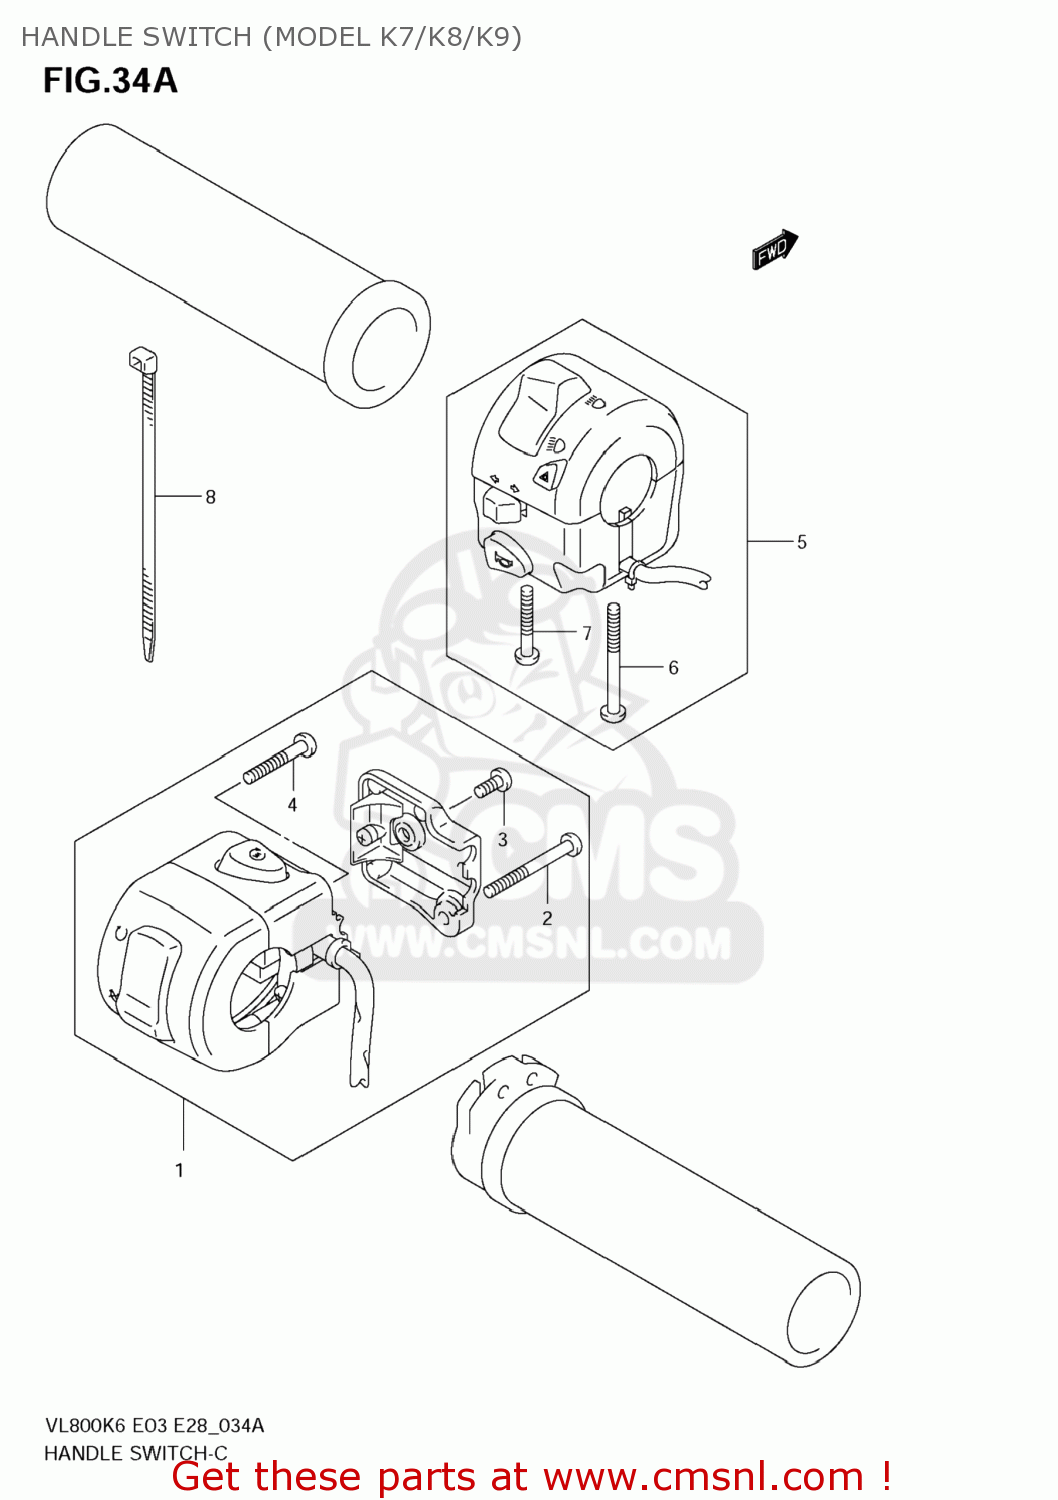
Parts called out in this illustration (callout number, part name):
1	STUURSCHAK.RH
2	SCREW
3	SCREW
4	SCREW
5	SWITCH ASSY,HANDLE,L
6	SCREW
7	SCREW
8	CLAMP(L:145)
